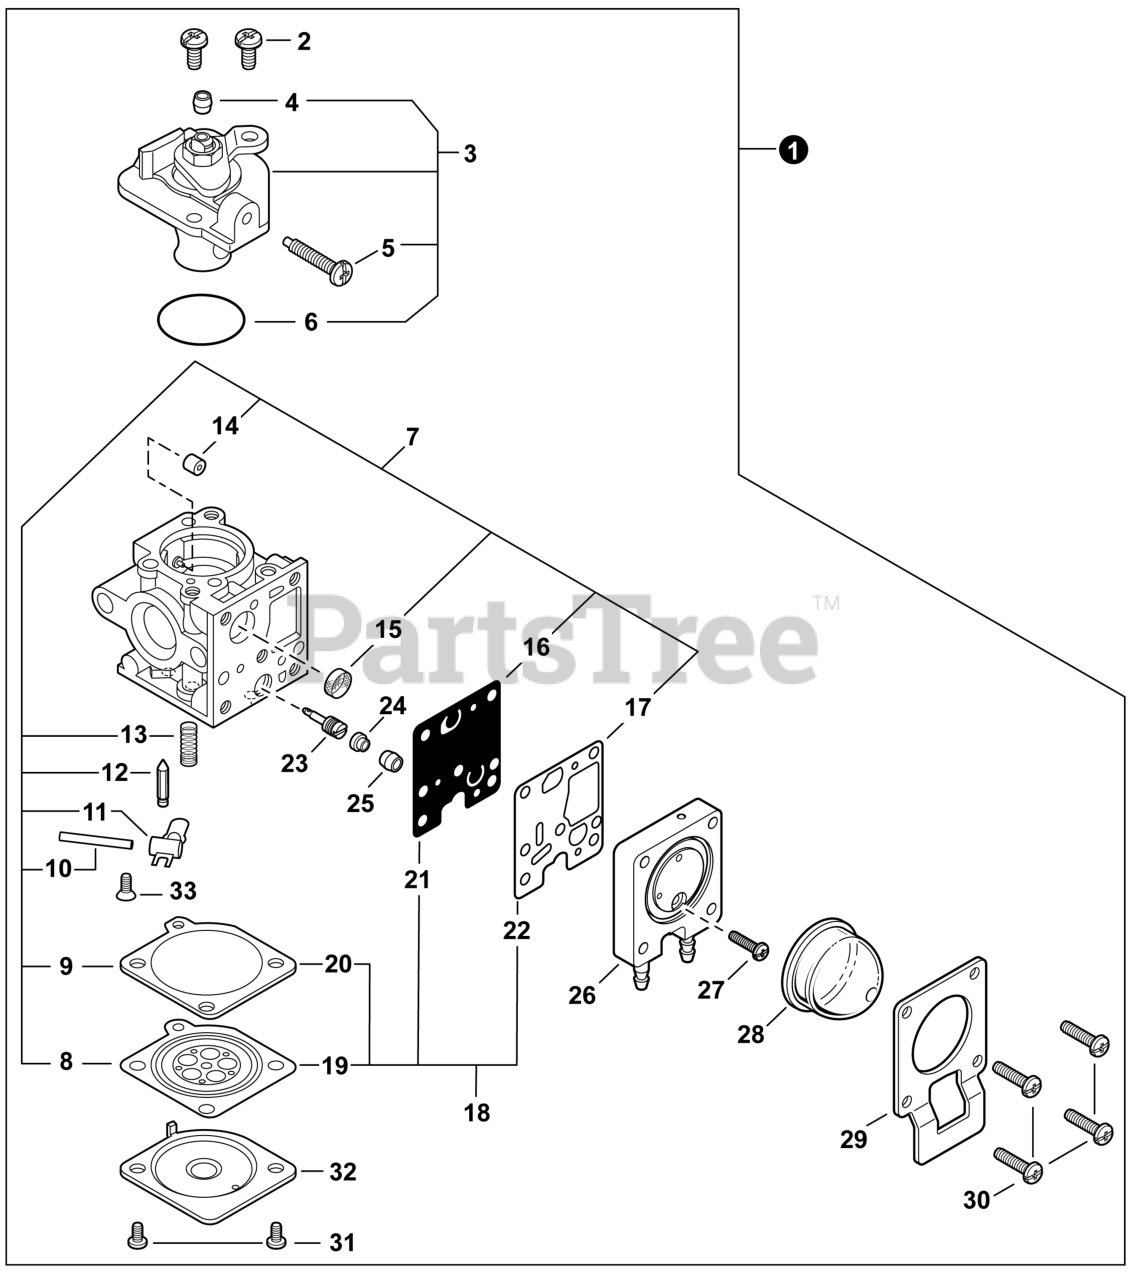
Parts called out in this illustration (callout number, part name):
1	CARBURETOR - Z011-0M(A)(B)
3	COVER ASSY, ROTOR
5	SCREW, IDLE ADJUST
7	REPAIR KIT, CARBURETOR
8	DIAPHRAGM, METERING
9	GASKET, METERING DIAPHRAGM
10	PIN, METERING LEVER
11	LEVER, METERING
12	VALVE, INLET NEEDLE
13	SPRING, METERING LEVER
14	GUIDE, ROLLER
15	SCREEN, FUEL INLET
16	DIAPHRAGM, PUMP
17	GASKET, PUMP
18	GASKET / DIAPHRAGM KIT
19	DIAPHRAGM, METERING
20	GASKET, METERING DIAPHRAGM
21	DIAPHRAGM, PUMP
22	GASKET, PUMP
23	NEEDLE, MIXTURE
24	CAP, LIMITER
26	BODY ASSY, PURGE
28	BULB, PURGE
29	RETAINER, PURGE BULB
32	COVER, METERING DIAPHRAGM
